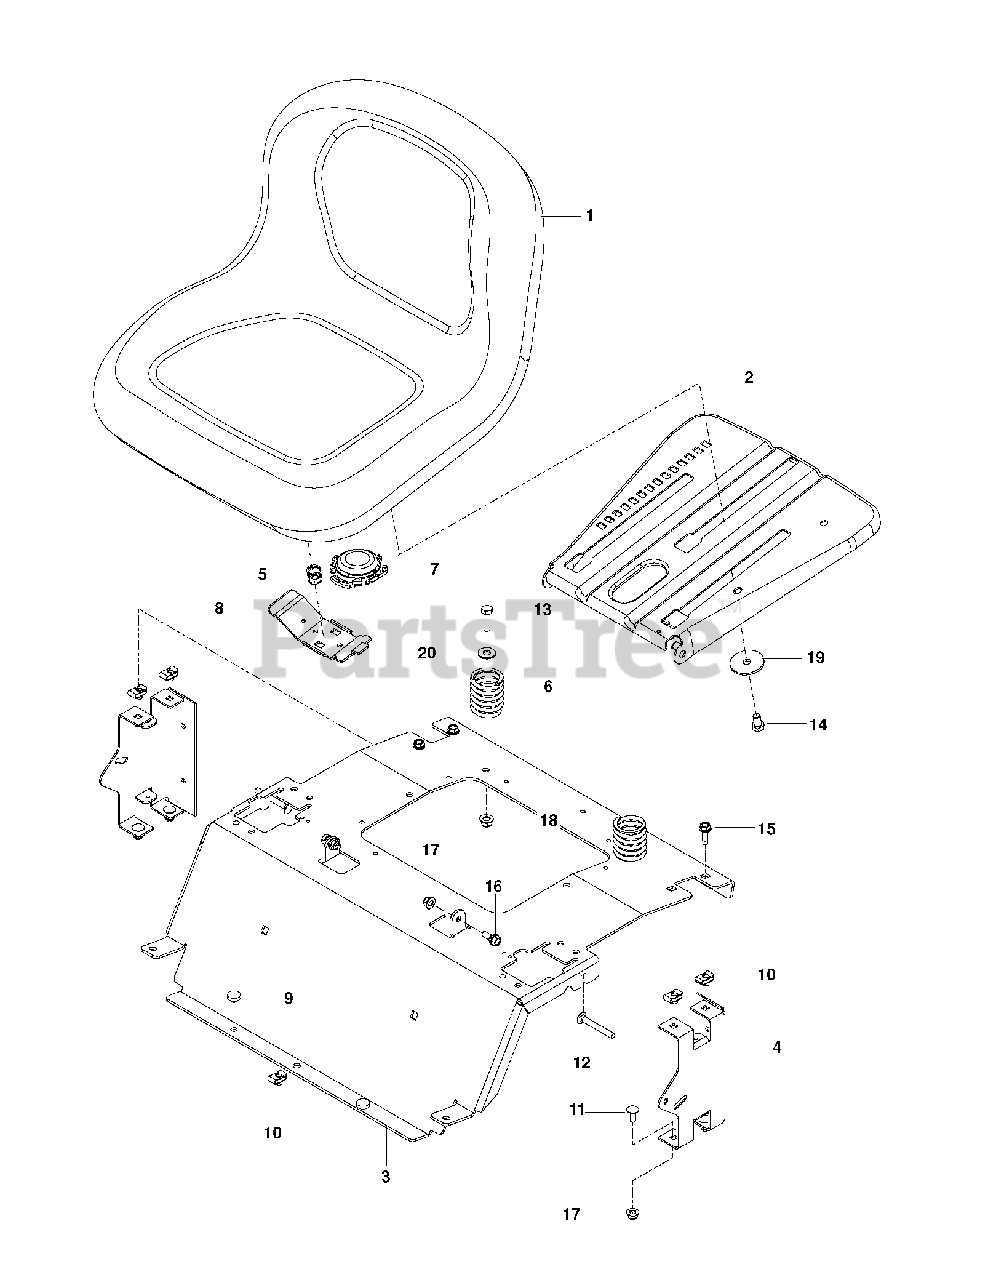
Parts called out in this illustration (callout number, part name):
1	SEAT.TG150.BLK.NLOGO.
2	PAN.ASM.SEAT.3PT
3	SUPPORT.PNT.SEAT.JN-RED
4	SUPPORT REAR SEAT BLACK
5	SPRING.LATCH.SEAT.TEX
6	SPRING COMPRESSION
7	SWITCH, SEAT N/C
8	HANDLE.SLIDE.SEAT.TEX.BLACK
9	GROMMET, BUMPER
10	U-CLIP 5/16-18 NUT RETAINER
11	BOLT 5/16C X 3/4" CARRIAGE
12	RHSNB 5/16-18 X 2-1/2 GR5 ZD
13	BOLT
14	HCS 3/8-16 X 5/8 GR 5 ZD
15	BOLT 5/16-18 X 3/4
16	BOLT, SHOULDER
17	5/16-18 NYLOC FLANGE NUT
18	NUT 3/8-16 HEX FLG NYLOC ZD
19	WASHER, 3/8 SPEC
20	WASHER 3/8 FLAT
